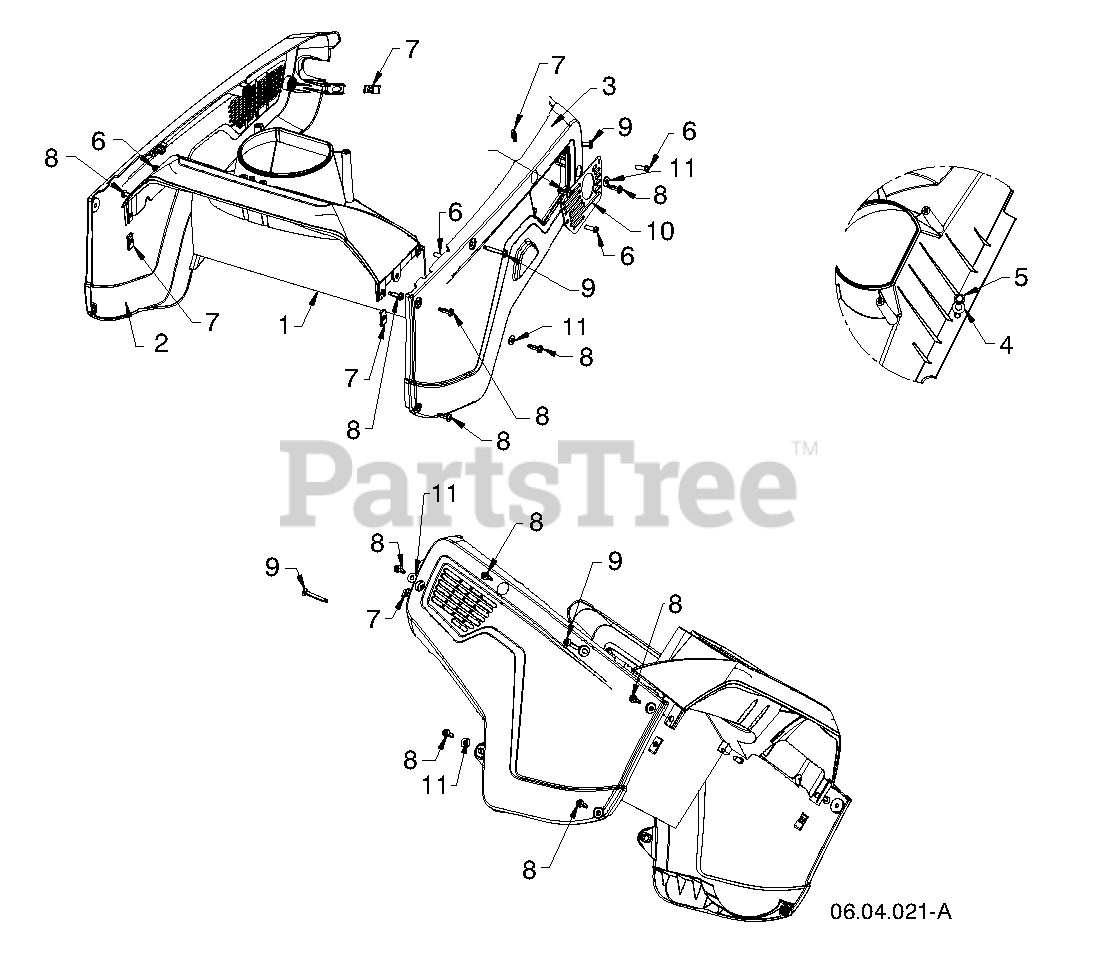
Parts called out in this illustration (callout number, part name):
1	AUGER.PLENUM.SINGLE.STAGE.GREY
2	COVER.NON-DRIVE.SIDE.HUS.ST151
3	COVER.DRIVE.SIDE.HUSQ.GY.ST151
4	WASHER
5	BOLT.HEX.HD.WASHER.5/16-18X.75
6	SCREW.HX.13X.750
8	SCREW.PAN.HD.TORX.1/4-20X.750
9	SCREW.1/4-20.PAN.HEAD.TORX.
10	PLATE.EXHAUST.SINGLE.STAGE.SNO
11	WASHER
